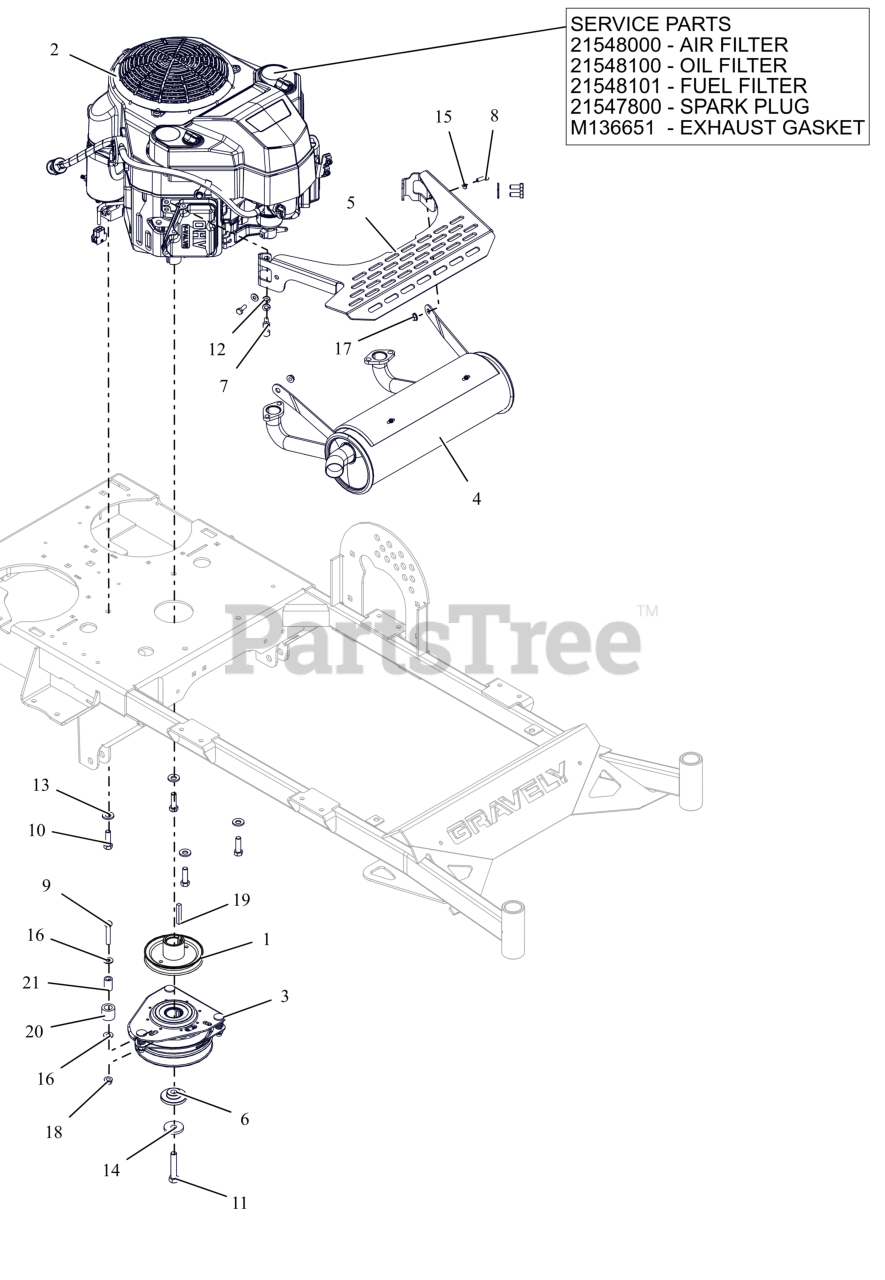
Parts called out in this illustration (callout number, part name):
1	SHEAVE, ENGINE 4.50 x 1.004 ID (BLACK)
2	ENGINE, KAWASAKI FS481
2	AIR FILTER, KAWASAKI FR
2	OIL FILTER, KAWASAKI FR
2	FUEL FILTER-KAWASAKI FR
2	SPARK PLUG, KAWASAKI FR
2	GASKET, MUFFLER #
3	CLUTCH, OGURA GT1A-AR03
4	MUFFLER, KAW FS PROWALK
5	SHIELD, MUFFLER
6	BSHG-FLG .469X1.06X.574X2.0
7	BLT, HEX M8-1.25X20 G8.8 ZCC
8	BLT, HEX .25-20X.75 G5 ZCC
9	BLT, HEX .31-18X1.75 G5 ZCC
10	BLT, HEX .38-16X1.25 G5 ZCC NT
11	BLT, HEX 0.4375-20X2.25 G8 ZCC NT
12	WSHR,LK-REG .312X.078 ZCC
13	WASHER, 3/8" SPRING DISC
14	WASHER, 7/16" SPRING DISK
15	WSHR,FLT .281X.625X.065 ZCC
16	WSHR, FLT .312X.734X.065 ZCC
17	NUT-LK-CTR-FLG .25-20 ZC120
18	NUT,LK-CTR-FLG .31-18 GF ZCC
19	KEY-STR .25X1.75X.25
20	BUMPER,RUBBER .62X1.0X.88 LG
21	BUSH.,S.391X.622X.950 ST
